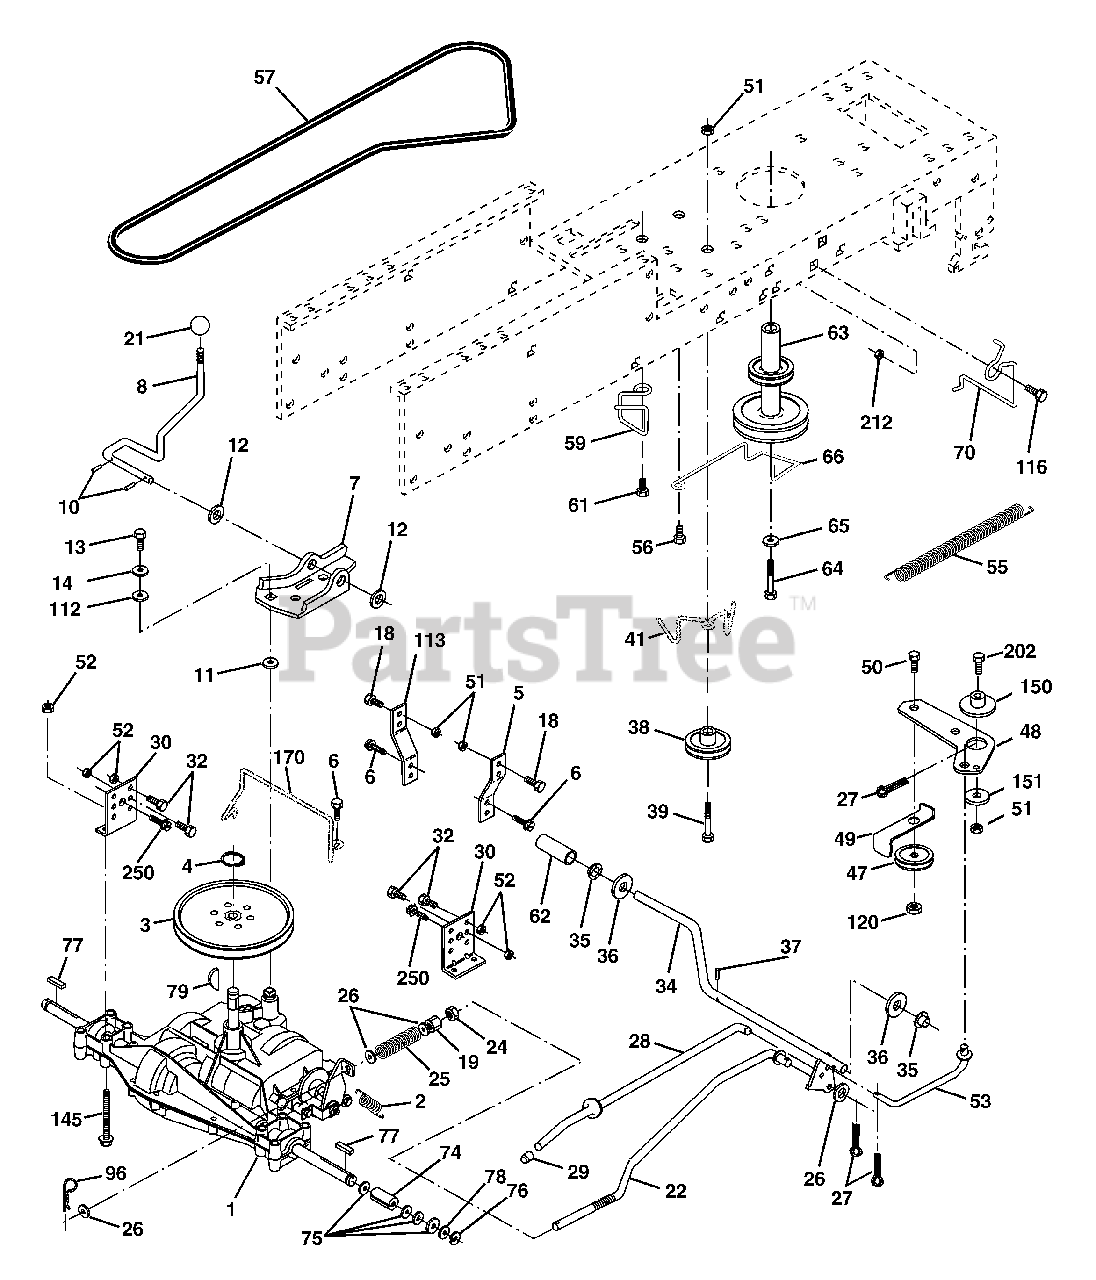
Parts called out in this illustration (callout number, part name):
2	Spring Return Brake
3	Pulley Transaxle 18" tires
4	Ring Retainer # 5100-62
5	Strap Torque 30 Degrees RH
6	Screw 5/16-18 x 3/4
7	Plate Rod Shift T/a
8	Rod Shifter Blk
10	Pin Cotter 1/8 X 1 Cad
11	Washer Plate Shf 388 Sq Hole
12	Washer 15/32 X 3/4 X 16 Ga
13	Bolt 1/4-28 unf Gr. 8 w/Patch
14	Washer Lock Hvy Helical 1/4
18	Bolt Fin Hex 3/8-16unc X 1 Gr. 5
19	Nut lock Hex w/Ins 3/8-16 Unc
21	Knob Rd 1/2-13 Plstc Thds Blk
22	Rod Brake LT
24	Nut Hex Jam 3/8-16 Unc
25	Spring Rod Brake 2 00 Zinc
26	Washer 13/32 X 13/16 X 16 Ga
27	Pin Cotter 1/8 X 3/4 Cad
28	Rod Brake Parking LT/YT
29	Cap Brake Parking Black
30	Bracket Transmission
32	Bolt Fin Hex 5/16-18 x 3/4
34	Shaft Asm Pedal Foot Nibbed
35	Bearing Nylon Blk 629 Id
36	Washer 21/32 X 1 X 16 Ga
37	Pin Roll 3/16 X 1"
38	Pulley Composite Flat
39	Bolt Fin Hex 3/8-16 x 3
41	Keeper Belt Idler
47	Pulley Idler V Groove Plastic
48	Bellcrank Clutch Grnd Drv STL
49	Retainer Belt Style Spring
50	Bolt Hex Hd 3/8-16unc X 1-1/2
51	Nut Crownlock 3/8-16 Unc
52	Nut Crownlock 5/16-18 unc
53	Link Clutch 7 66
55	Spring Return Clutch 6 75
56	Screw 3/8-16 x 1-1/4
57	V-Belt Ground Drive 95
59	Keeper Belt Chassis Span Ctr
61	Screw 3/8-16 x .875
62	Cover Pedal Blk Round
63	Engine Pulley LT/YT
64	Bolt Hex 7/16-20x4 Gr 5
65	Washer Lock Hvy Hlcl Spr 7/16
66	Keeper Belt Engine
70	Guide Belt Mower Drive RH
74	Spacer Axle
75	Washer 25/32 X 1 1/4 X 16 Ga
76	E-ring #5133-75
77	Key Square 2 0 X 1845/ 1865
78	Washer 25/32 X 1-5/8 X 16 Ga
79	Key Woodruff
96	Retainer Spring 1"
112	Washer 9/32 X 3/4 X 10 Ga
113	Strap Torque 90 Degrees LH
116	Bolt Rdhd Sq Neck 3/8-16 x 1
120	Nut Lock Flg 3/8-16
145	Bolt Hex Flg.Hd. 5/16-18 x Gr.5
150	Spacer Retainer Lt
151	Washer 13/32 x 2 x 10 Ga.
170	Keeper, Belt Transaxle Gear
202	Bolt Carr Sh 3/8-16 x 1-3/4 Gr.5
212	Nut Hex Flg Lock
250	Screw 3/8-16 x 3/4
